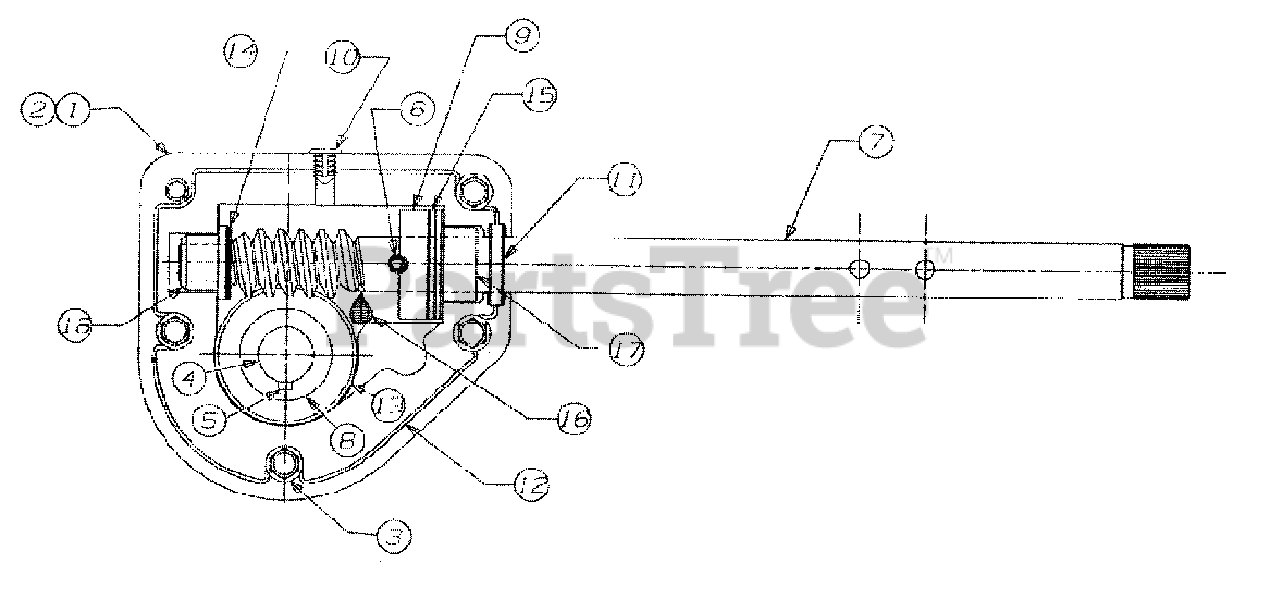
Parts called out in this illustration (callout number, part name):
1	Housing-R.H.
2	Housing-L.H.
3	Screw
4	Axle, Spiral 30" (663)
4	Axle, Spiral 26" (653)
4	Axle, Spiral 24" (633)
4	Axle, Spiral 22" (623)
5	Key, Hi-Pro
6	Pin, Spiral
7	Worm, Shaft
8	Gear, Worm
9	Collar, Thrust
11	Seal, Oil
12	Loctite 5699
13	Washer-Flat
14	Washer-Flat
15	Washer-Flat
16	Grease
17	Bearing Flange
18	Bearing Flange
